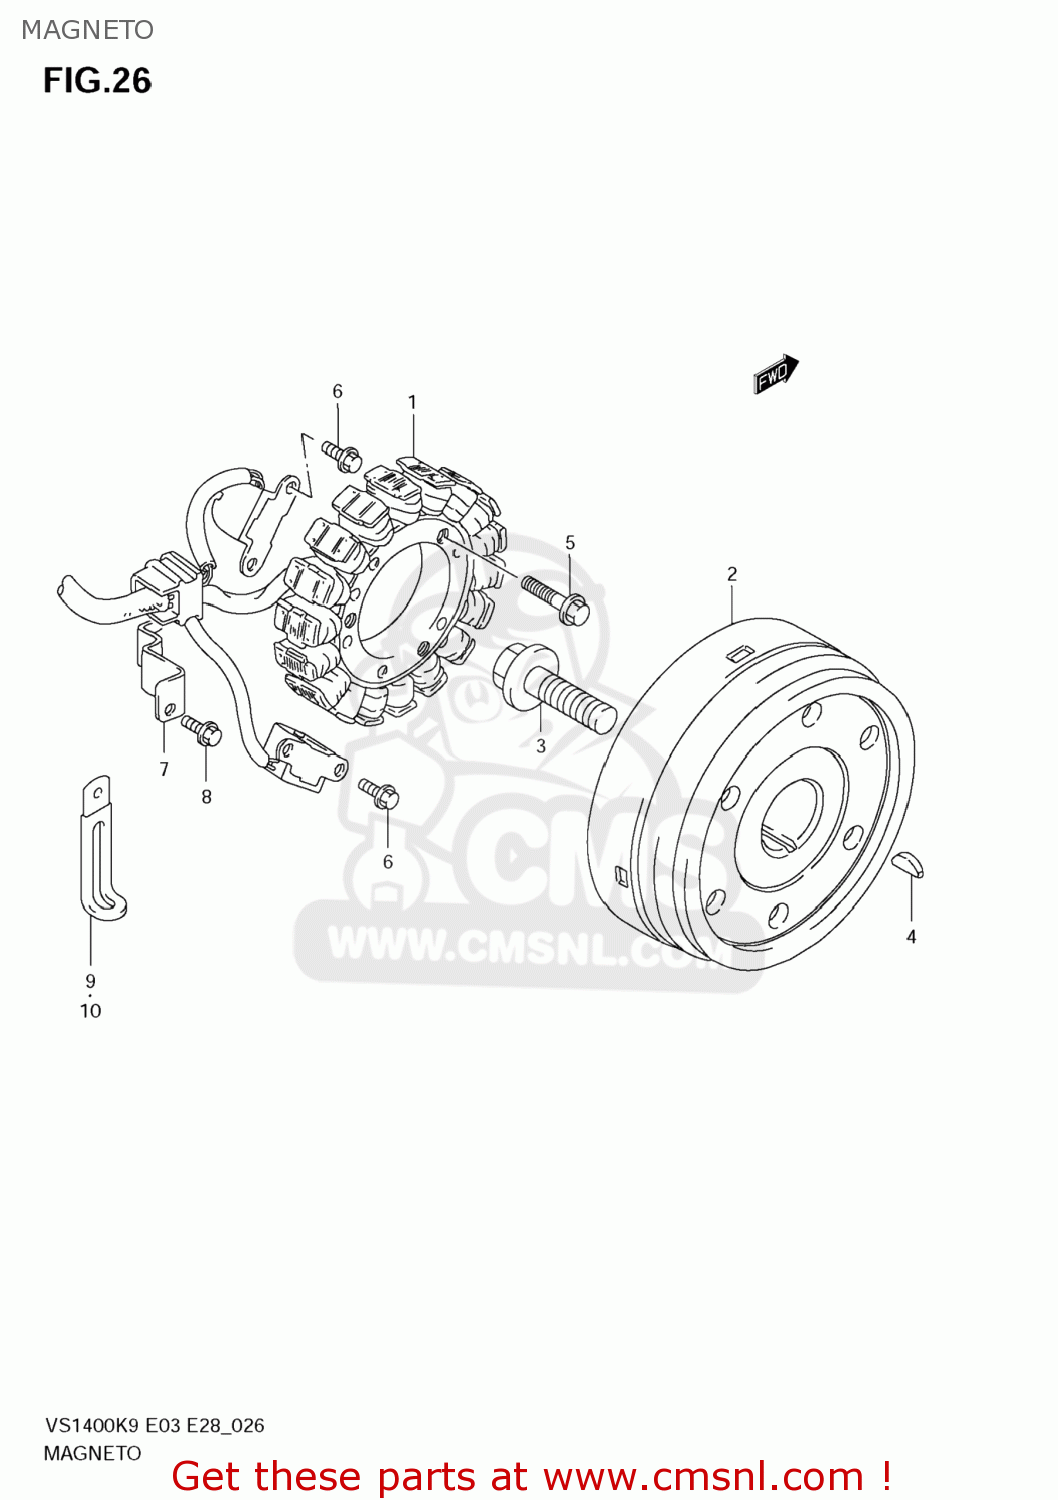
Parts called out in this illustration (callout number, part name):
1	STARTER ASSY
2	ROTOR ASSY
3	BOLT(14X43)
4	KEY
5	BOLT
6	BOLT
7	CLAMP,MAGNETO LEAD WIRE
8	BOLT
9	CLAMP(L:80)
10	CLAMP(L:45)
